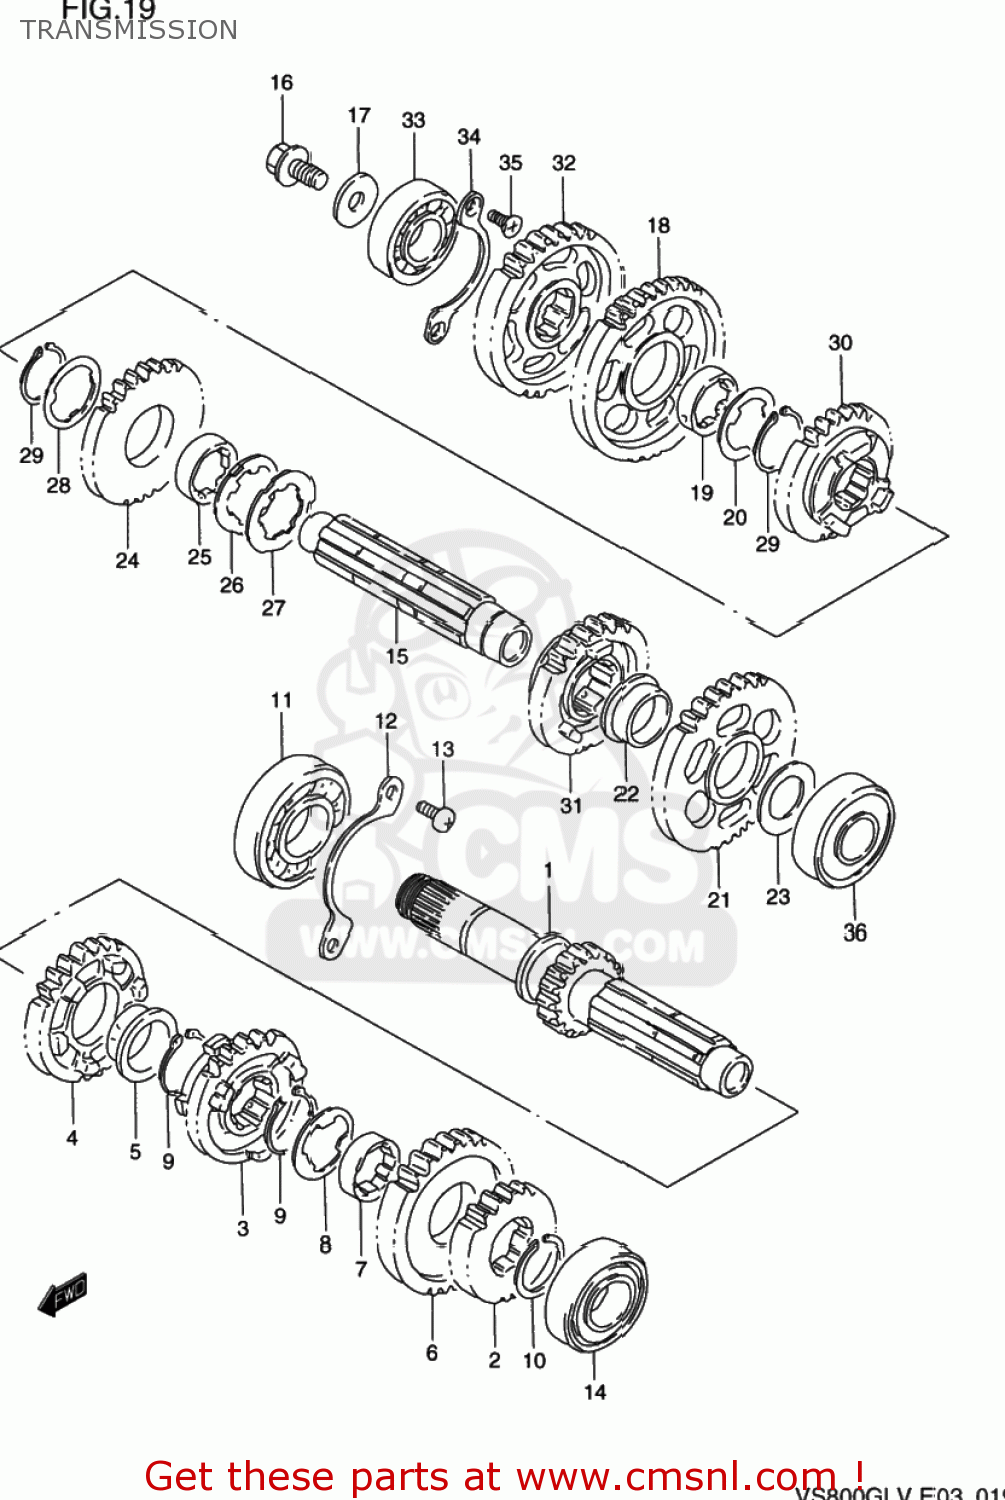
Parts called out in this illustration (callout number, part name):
1	COUNTER SHAFT
2	GEAR,2ND DRIVE(NT:19)
3	GEAR,THIRD DRIVE
4	GEAR,4TH DRIVE(NT:25)
5	BUSHING
6	GEAR,FIFTH DRIVE (NT:27)
7	BUSHING
8	WASHER,LOCK
9	RING,SNAP
10	CIRCLIP
11	BEARING(25X62X17)
12	RETAINER,CNTR SHAFT BEARING
13	SCREW
14	BEARING 20X47X14
15	SHAFT,DRIVE
16	NOZZLE,DRIVE SHAFT
17	WASHER
18	GEAR,1ST DRIVEN(NT:32)
19	BUSH
20	WASHER,LOCK
21	GEAR,2ND DRIVEN(NT:31)
22	BUSH
23	WASHER
24	GEAR,3RD DRIVEN(NT:27)
25	BUSH
26	WASHER
27	WASHER,LOCK
28	WASHER,LOCK
29	CIRCLIP
30	GEAR,FOURTH DRIVEN
31	GEAR,FIFTH DRIVEN
32	GEAR,REDUCTION DRIVE(NT:30)
33	BEARING(20X52X15)
34	RETAINER,DRIVE SHAFT BEARING
35	SCREW
36	BEARING(20X52X15)
